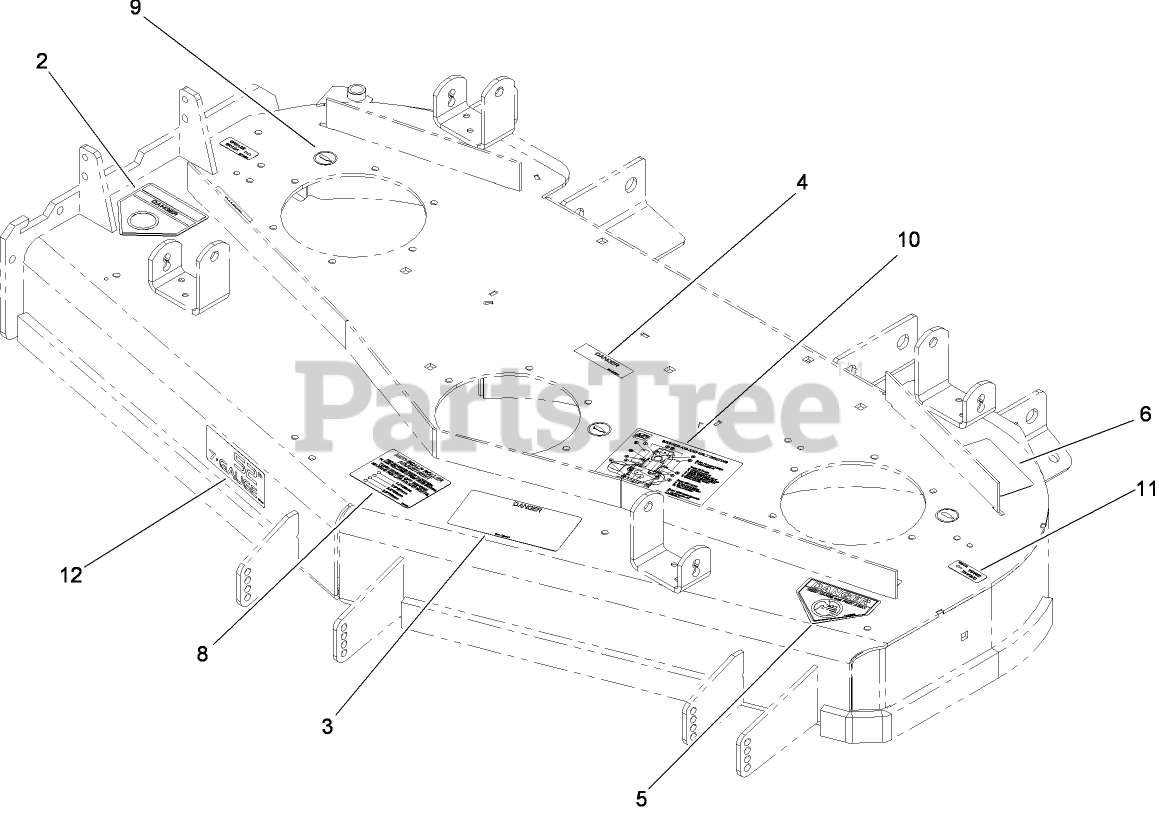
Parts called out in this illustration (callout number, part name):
2	DECAL-DANGER
3	DECAL-DANGER, THROWN OBJECT
4	DECAL-COVER, MISSING
5	DECAL-DANGER
6	DECAL-TORQUE
8	DECAL-SCALP, ANTI
9	DECAL-GREASE
10	DECAL-AID, SERVICE
11	Decal-Grease
